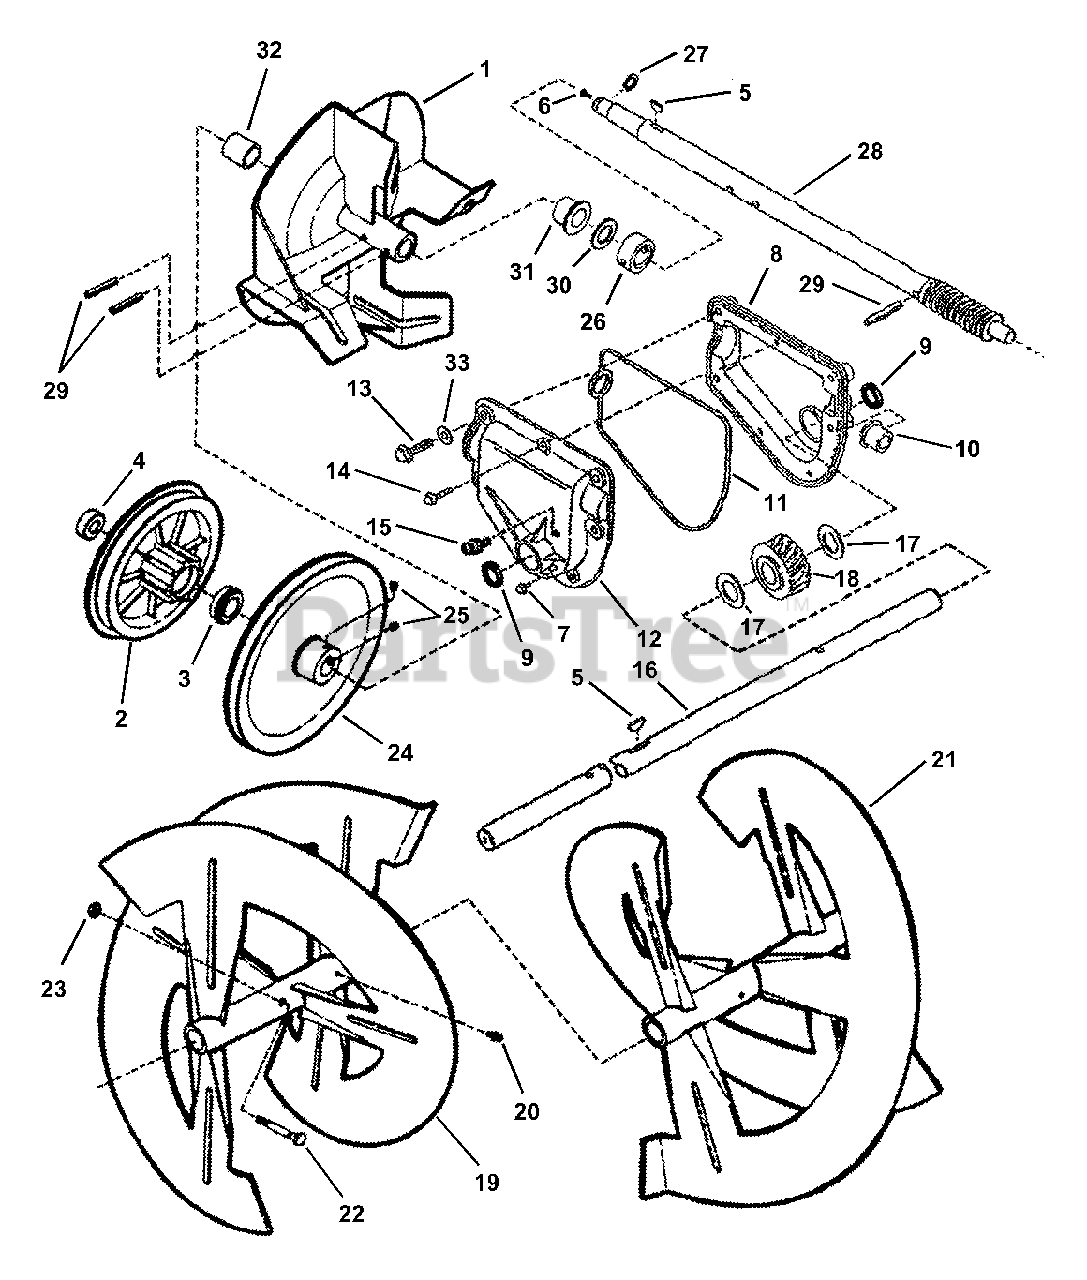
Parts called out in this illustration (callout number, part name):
1	WELDMENT, Impeller (Fan)
2	ASSEMBLY, Drive Plate
3	BEARING, Ball
4	BEARING, Ball
5	KEY, #9 (3/16 x 3/4") Woodruff
6	SCREW, 1/4-20 x 1/2" Truss Head Self-Tapping (Torx)
7	SCREW, #10-24 x 1/2" Hex Washer Self-Tap (Torx)
8	COVER, Gear Case (Left Hand)
10	BUSHING
11	"O" RING
12	COVER, Gear Case (Right Hand)
13	SCREW, 1/4-20 x 3/4" Hex Washer Self-Tapping
14	SCREW, #10-24 x 5/8" Hex Washer Self-Tap, Grade 5
15	LUBE FITTING, 1/4-28 Thread Forming
16	SHAFT, Auger
17	WASHER, Thrust
18	GEAR, Worm
19	AUGER, (Left Hand)
20	LUBE FITTING, Straight (press-fit for .187 dia. Hole)
21	AUGER, (Right Hand)
22	PIN, Shear, .248 ID. X 1.75 LG
23	COTTER PIN, .094 X0.750 BLK
24	PULLEY, 8.36" O.D.
25	SCREW, 5/16-18 x 5/16 Hex Socket Set
26	COLLAR
27	RING, 1/2" Heavy Duty External Retaining
28	SHAFT, Pinned Impeller (Worm)
29	ROLL-PIN, 1/4 x 1-1/4"
30	WASHER, Thrust
31	BEARING
32	SPACER, .76 I.D. x 1" O.D. x .25" Thick
33	WASHER, Shim
